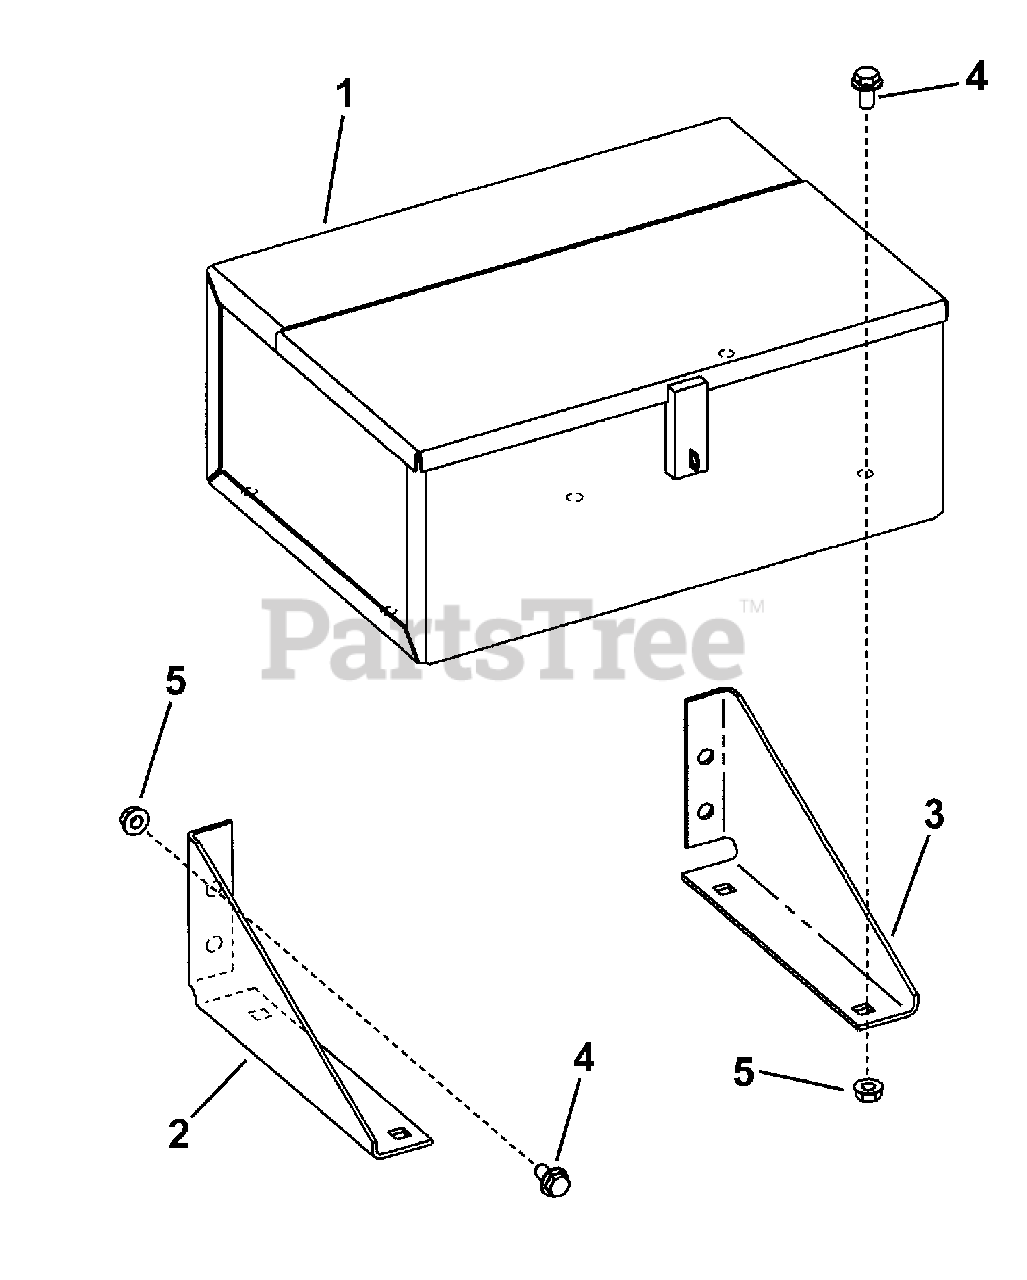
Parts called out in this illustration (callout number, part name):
1	TOOLBOX, Turf/Trail Cruiser
2	BRACKET, Toolbox, LH
3	BRACKET, Toolbox
4	BOLT, Hex Flange Lock, 5/16-18 x 5/8 GR 5
5	NUT, Hex Flange Lock, 5/16-18 GR 5
